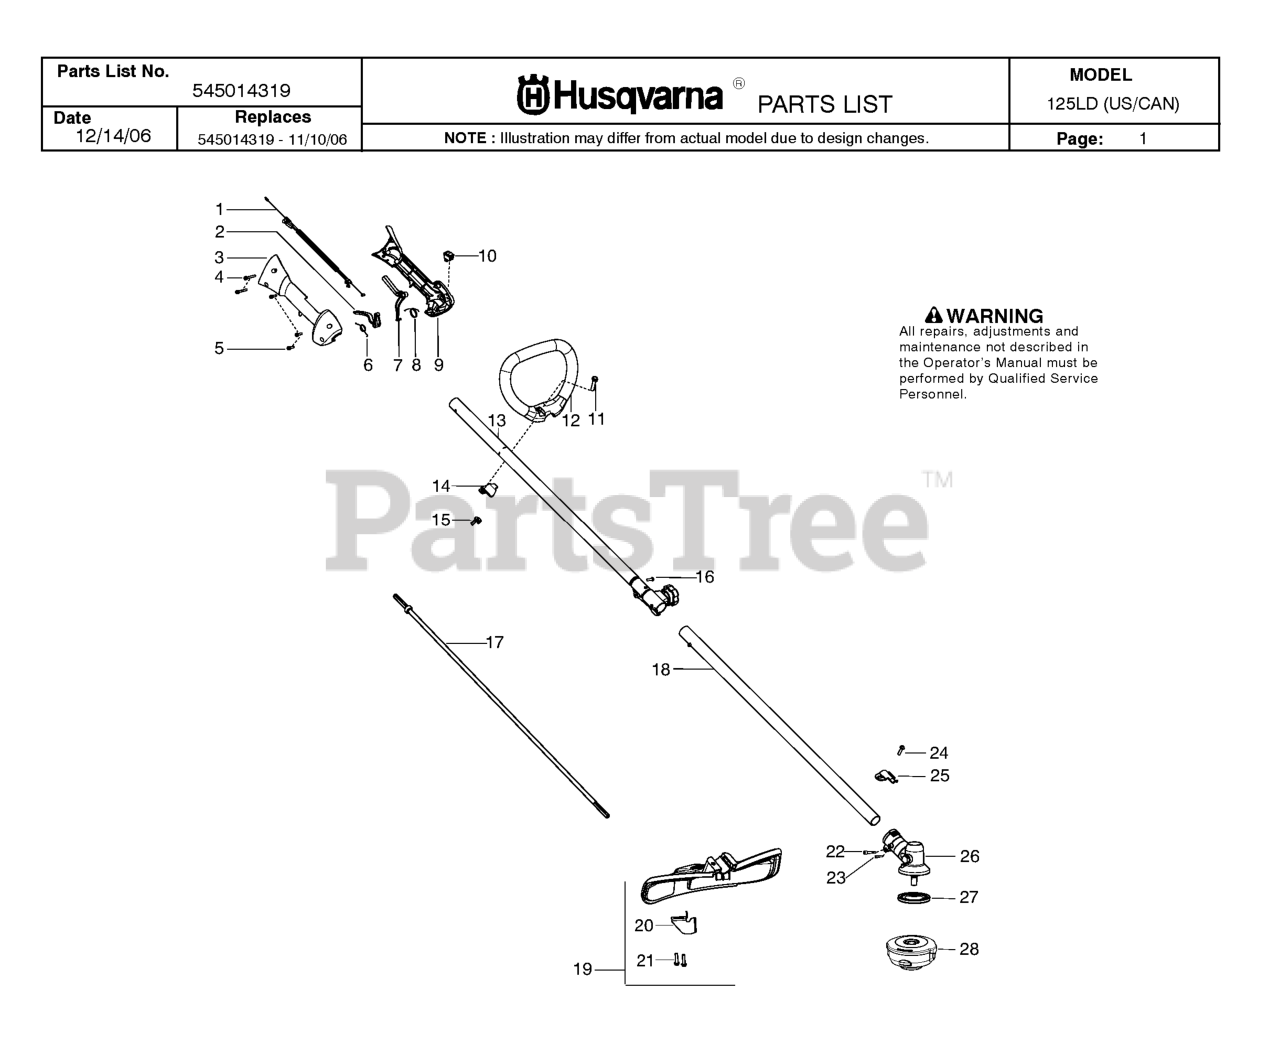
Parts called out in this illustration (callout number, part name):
2	TRIGGER THROTTLE
3	HOUSING-THROTTLE RH
5	SCREW M4 X 1.75 PT 16MM
6	SPRING TRIGGER
7	THROTTLE LOCKOUT
8	SPRING LOCKOUT
9	HSG THROTTLE LH
10	KIT SWITCH
11	BOLT, TYPE 2
13	KIT-DRIVESHAFT UPPER INC DECAL
14	CLAMP ASSIST HANDLE
15	WINGNUT, TYPE 2
17	FLEX-LOWER
18	HSG DRIVESHAFT LOWER
19	KIT COBI SHIELD
20	Limiter - Line
22	SCREW - CARB. ADAPTOR
24	SCREW 1/4-20 X 7/8 (TAP
25	BRACKET SHIELD STRAIGHT SHAFT
26	ASSY GEARBOX
27	DRIVE DISC
28	T25 10MM LH TRIMMER HEAD
545096701	DECAL SHAFT WARN LOWER ROW
545096901	DECAL SHAFT WARNING UPPER US
